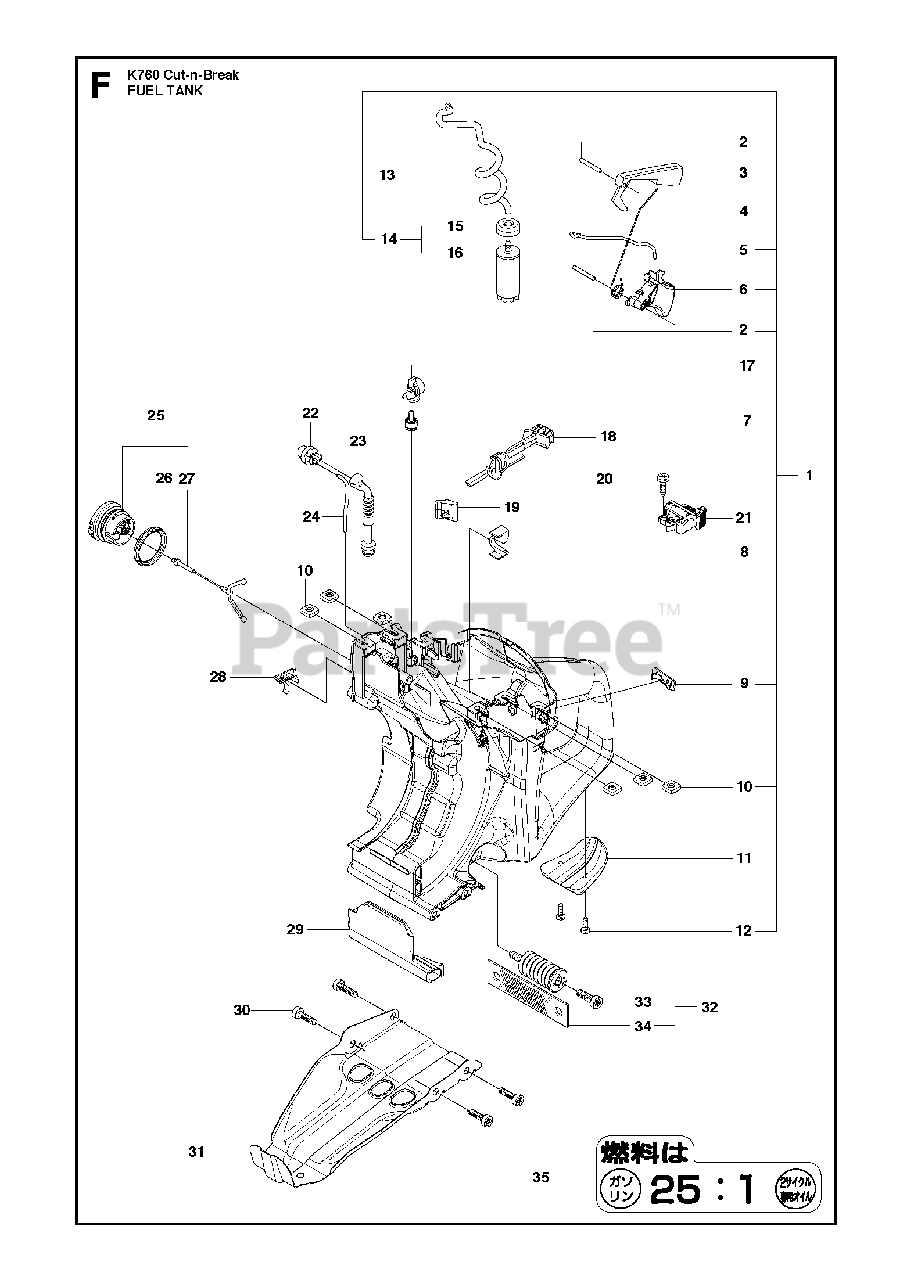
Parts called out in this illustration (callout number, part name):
1	FUEL TANK ASSYIncl. 2 - 14, 17
2	PARALLEL PIN
3	THROTTLE LOCKOUT
4	SPRING
5	THROTTLE ROD
6	THROTTLE CONTROL
7	TANK VENT ASSY
11	GROUND SUPPORT
12	SCREW CRCSFT
14	FUEL FILTERIncl. 15 - 16
17	TANK VENT VALVE ASSY
18	CHOKE CONTROL
20	SCREW CCRPANT
21	STOP SWITCH
23	FUEL HOSEPurge
24	FUEL HOSEPurge
25	TANK CAP ASSYIncl. 26 - 27
26	SEALING
30	SCREW ITXSCT
32	ANTIVIBRATION ELEMENTIncl. 33 - 34
33	SCREW ITXSCM
35	LABELJapan only
